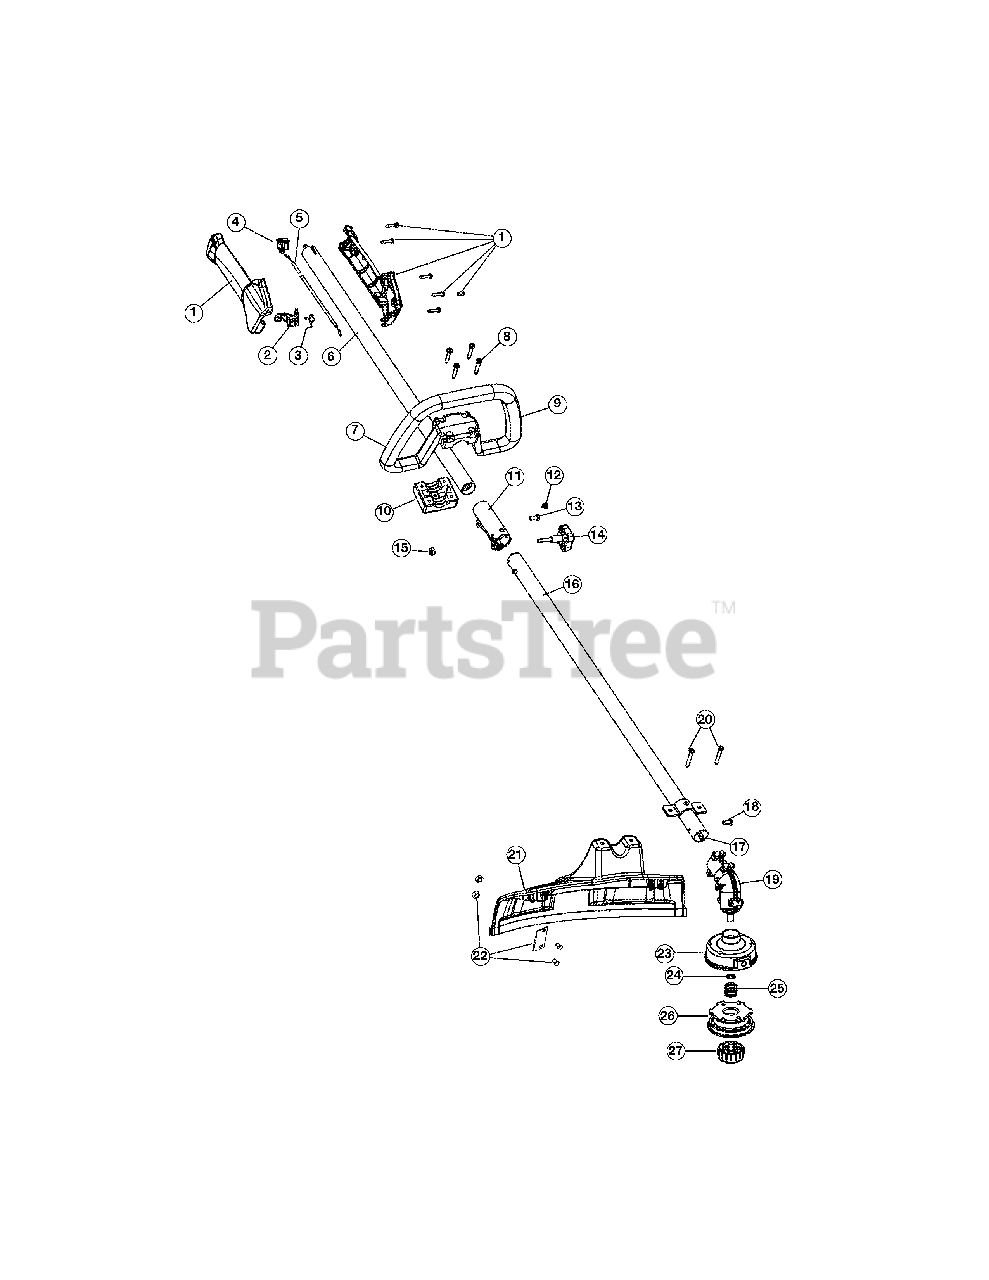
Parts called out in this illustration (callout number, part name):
1	Throttle Housing Assembly (Incl. Ref No. 2-4)
2	Throttle Trigger
3	Throttle Trigger Spring
5	Throttle Cable Assembly
6	Upper Drive Shaft Housing Assembly
7	Deluxe D-Handle Assembly (Incl. Ref No. 8-10)
9	D-Handle
10	Bottom Clamp
11	Split Boom Coupler (Incl. Ref No. 12-15)
14	Adjustment Knob (Incl. Ref No. 15)
15	Knob Retaining Nut
16	Lower Drive Shaft Housing Assembly
17	Lower Flexible Drive Shaft
18	Anti-Rotation Screw
19	Gear Box Assembly (Incl. Ref No. 18 & 23-27)
20	Shield Mounting Screws
21	Shield Assembly (Incl. Ref No. 22)
22	Blade Assembly
23	Outer Spool Assembly
24	Retainer
26	Inner Reel
27	Bump Knob Assembly
